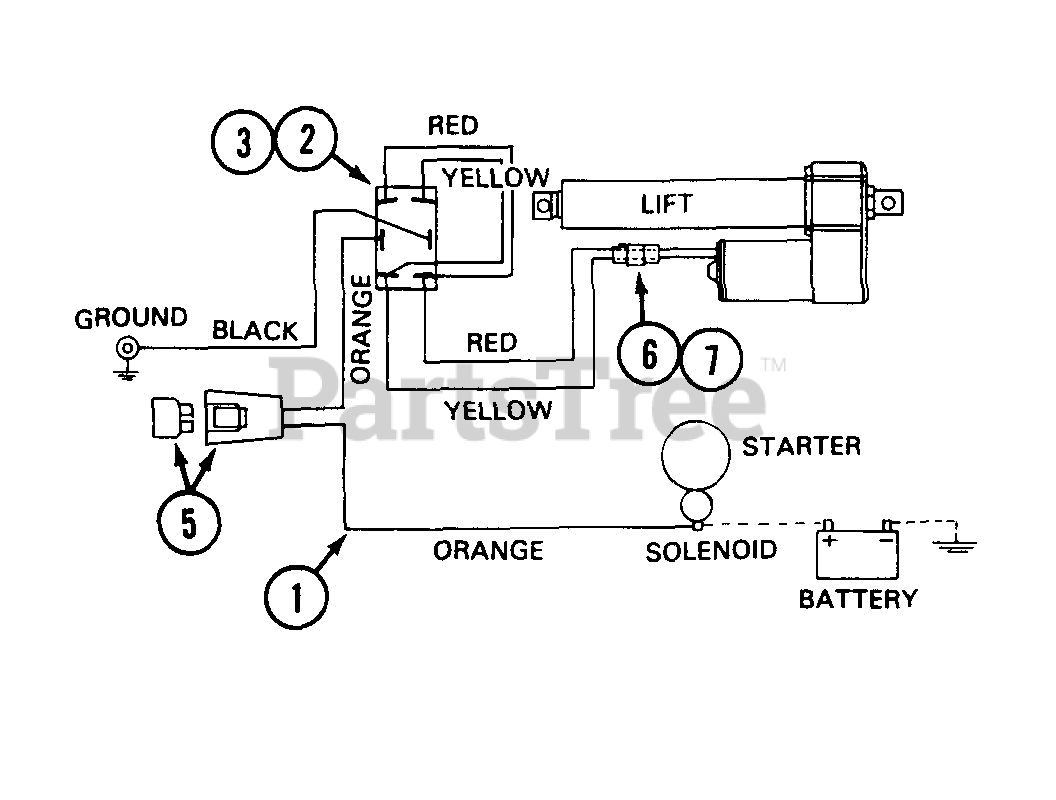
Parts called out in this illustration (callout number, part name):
1	HARNESS - wire
3	NUT - 15/32" - 32 with boot (switch mounting)
5	HOLDER - fuse
6	CONNECTOR - wire harness
7	CONNECTOR - lift actuator
